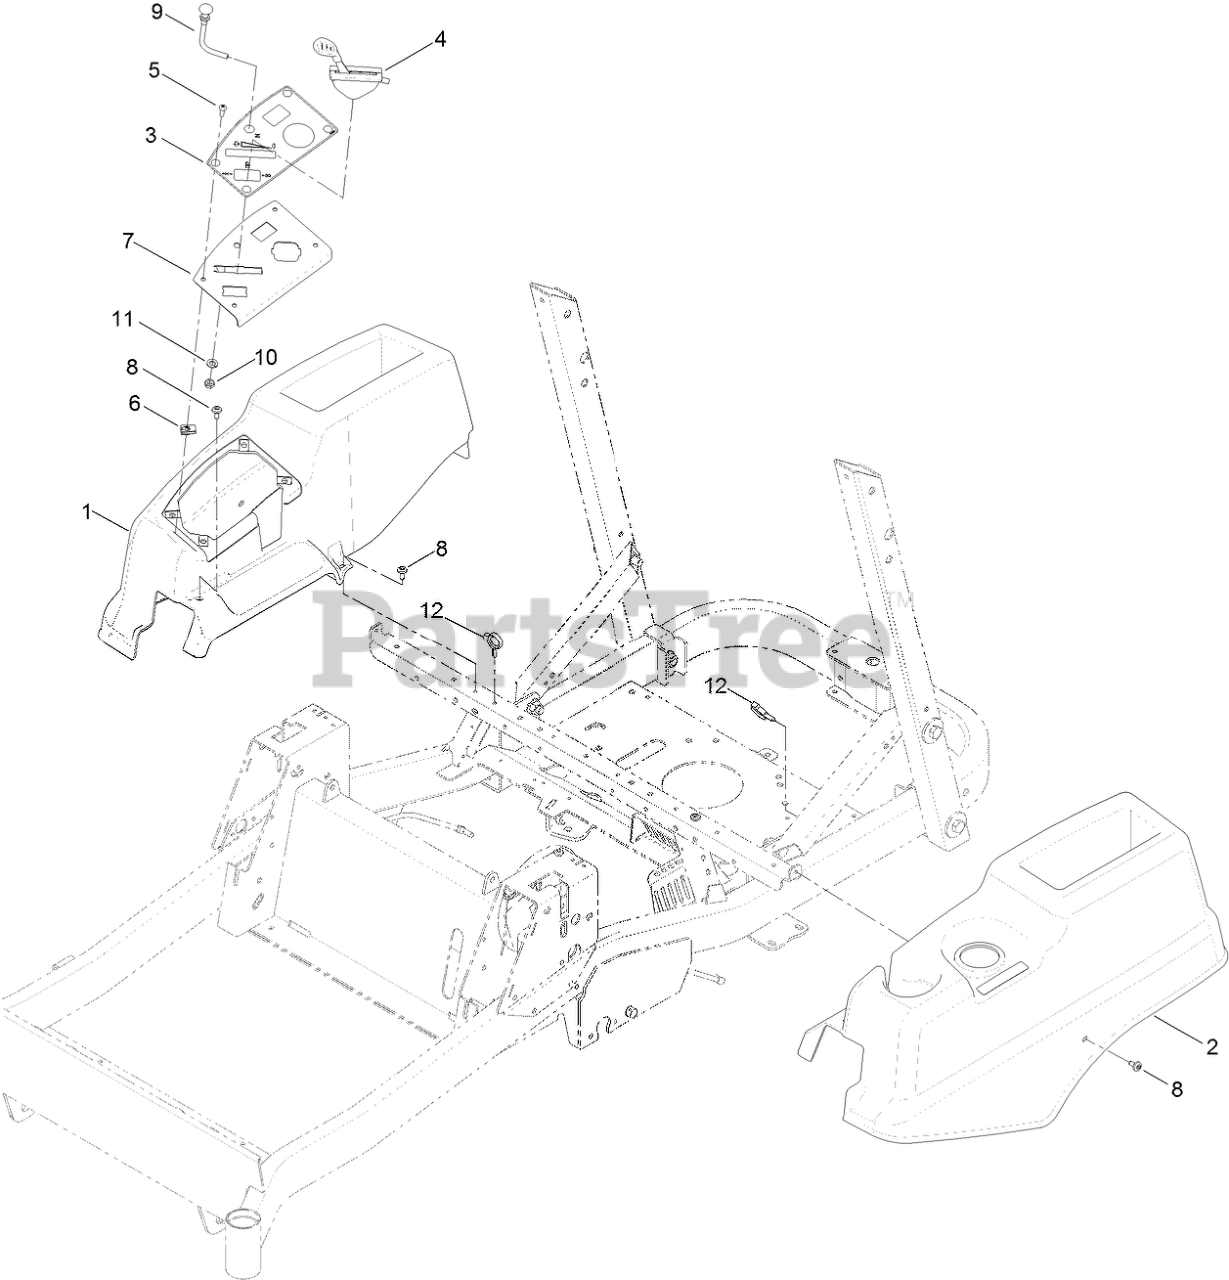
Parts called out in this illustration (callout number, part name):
1	POD-RH
2	POD-LH
3	DECAL-PANEL, CONTROL
4	CABLE-THROTTLE
5	SCREW-PRH
7	PANEL-CONTROL
8	SCREW-SHOULDER
9	CABLE-CHOKE
10	WASHER-LOCK
11	NUT-HJ
12	CLAMP-HOSE
